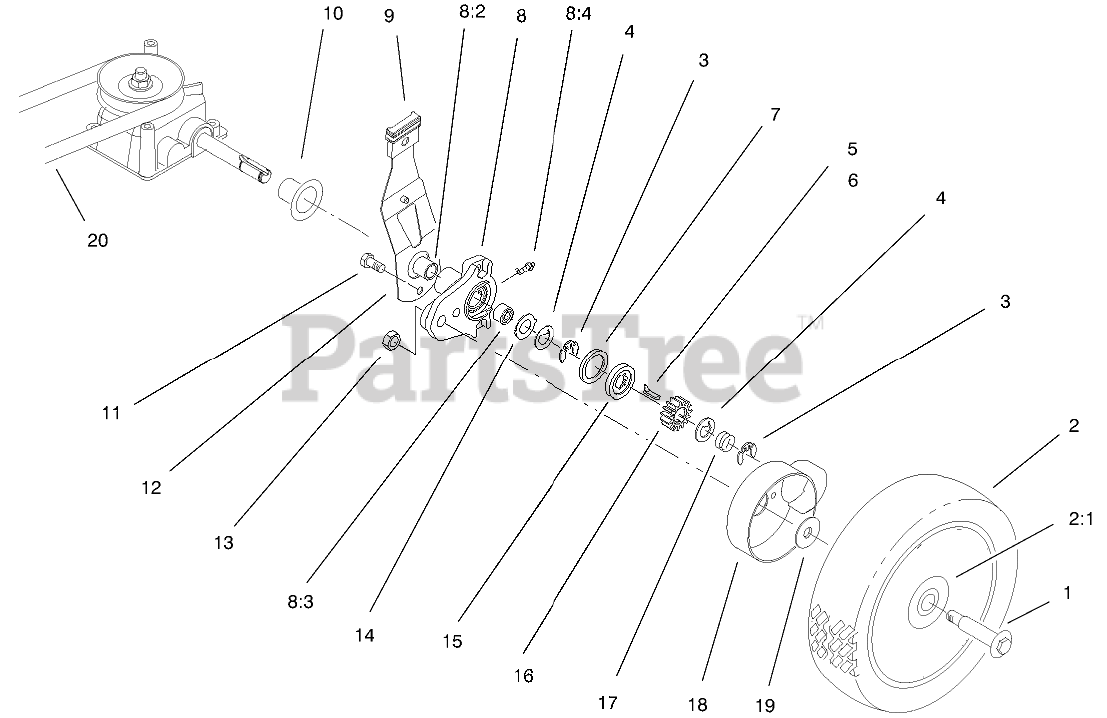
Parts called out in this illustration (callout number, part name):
1	BOLT-SHOULDER
2	WHEEL ASM
2:3	Wheel ASM
2:3:1	BUSHING
3	RING-CLIP, LOCKING
4	WASHER-THRUST, KEYED
5	KEY-ROCKING, RH
6	KEY-ROCKING, LH
7	RING-FRICTION
8	PIVOT ARM ASM
8:2	BUSHING
8:3	BUSHING
8:4	FITTING-GREASE
9	KNOB-ARM
10	CAP-END
11	SCREW-HWH
12	SPRING ARM ASM
14	WASHER-ARM, PIVOT
15	WASHER-CLUTCH
16	GEAR-PINION
17	SPRING-COMPRESSION
18	COVER-WHEEL
19	SPACER-COVER, WHEEL
20	BELT-V
